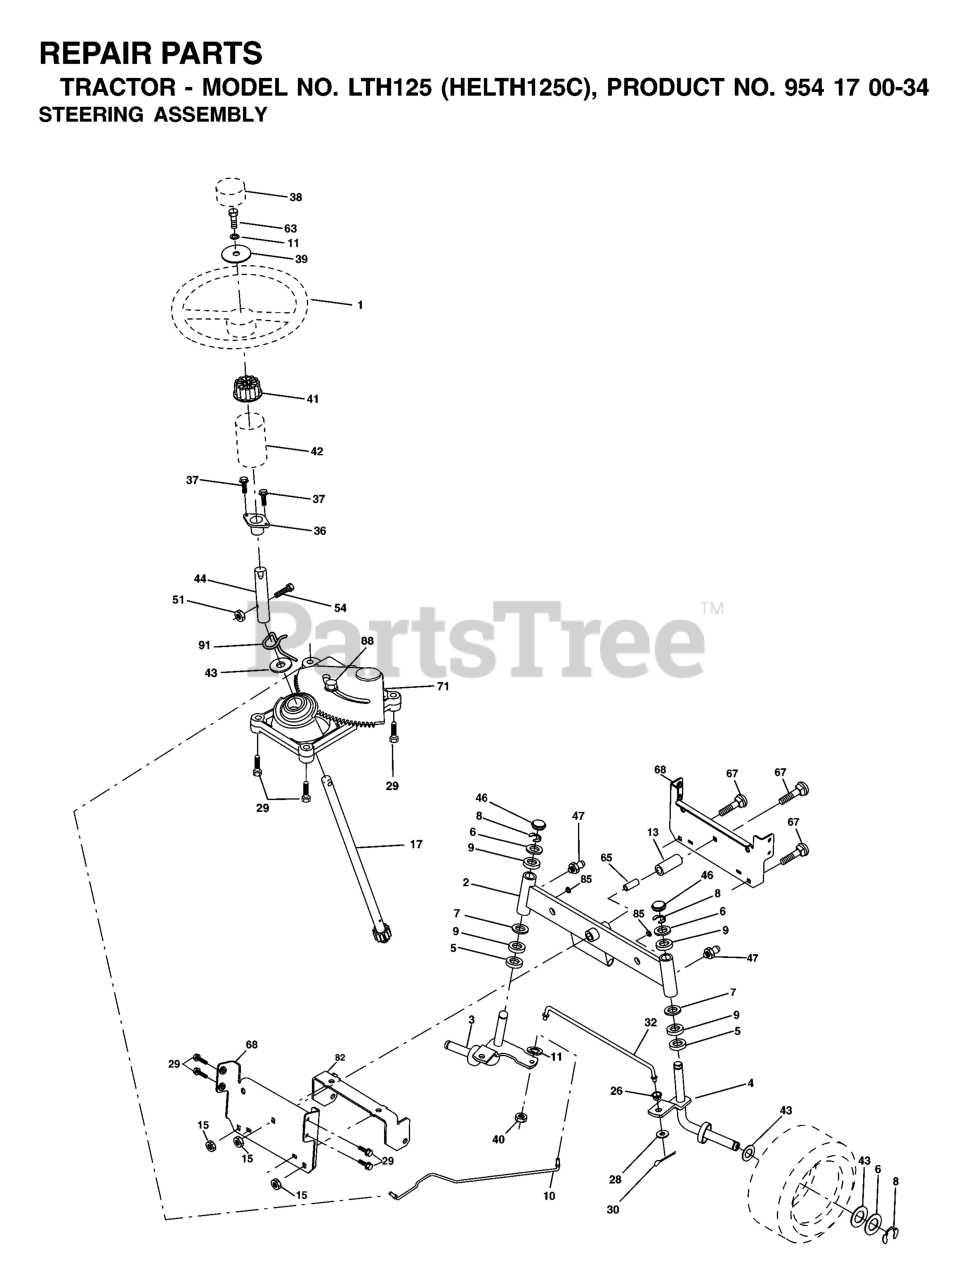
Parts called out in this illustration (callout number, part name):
1	STEERING WHEEL
2	AXLE ASM.
3	SPINDLE.ASM.LH.15"TIRES
4	SPINDLE.ASM.RH.15"TIRES
5	THRUST WASHER
9	BRNG T
10	DRAGLINK.15".TIRES.2001
11	WASHER, LOCK 3/8
13	TUBE, PIVOT AXLE
15	NUT
17	SHAFT ASM
26	BUSHING.DRAGLINK (2 2)
28	WASHER
29	SCREW 3/8-16X3/4
30	COTTER PIN
32	TIE ROD
36	BUSHING, STEERING
37	SCREW.TT.#10-32X.5.3/8.FLANGE
38	INSERT,STR WHEEL
39	WASHER 13/32 X 2-3/8 X 12GA
40	GRIPCO NUT
41	ADAPTER LT
42	BOOT STEERING
44	EXT SHAFT STEERING
46	CAP.SPINDLE.BLACK
47	ZERK M
51	NUT.71038.31-18.HEX.NYLOCK
54	BOLT.5/16-18X1-1/4 FULL.THREAD
65	SPACER BRACE AXLE
67	BOLT
68	BRACE.AXLE.15"TIRES
71	STEERING ASM
82	BRACKET
85	FASTENER.XMAS.TREE
88	BOLT, SHOULDER 7/16-20
91	CLIP.STEERING
